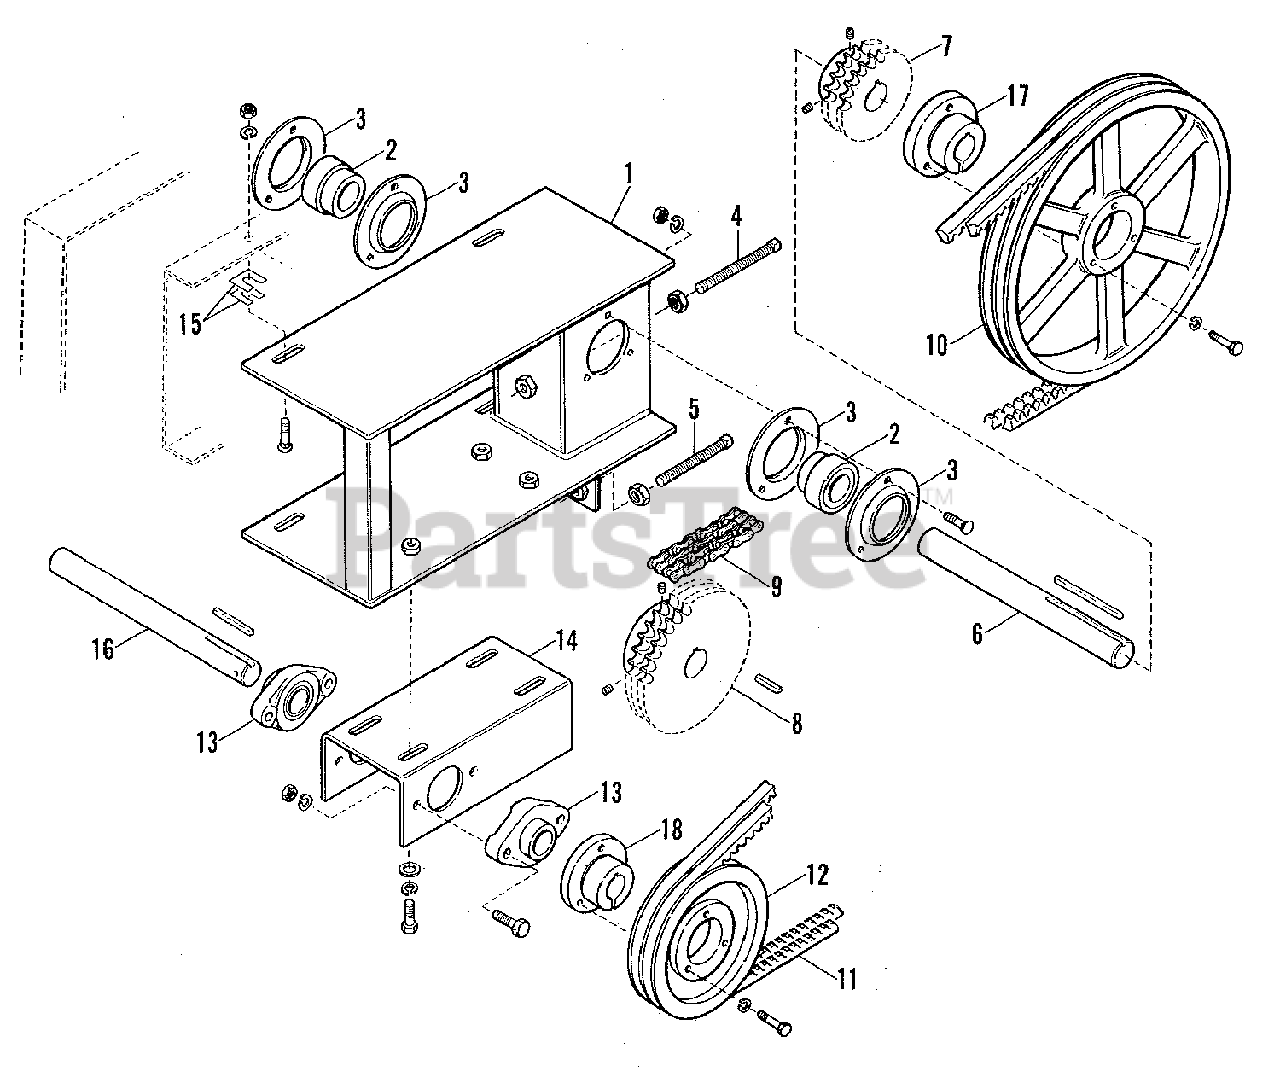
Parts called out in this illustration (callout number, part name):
1	FRAME ASSEMBLY, Mounting
1	BOLT, Carriage, 3/8NC x 1-1/4
1	LOCKWASHER, 3/8
2	BEARING, Reduction Drive Shaft (1-1/4" Bore)
3	FLANGE, Bearing
3	BOLT, Carriage, 3/8NC x 3/4
3	LOCKWASHER, 3/8
4	SETSCREW, 1/2NC x 5
5	SETSCREW, 1/2NC x 4
6	SHAFT, Reduction (Driven)
6	KEY, Square, 1/4 x 1/4 x 3-1/2
7	SPROCKET ASSEMBLY (Double -17T)
7	SETSCREW, Socket Head, 3/8NC x 3/8
8	SPROCKET ASSEMBLY (Double -36T)
8	SETSCREW, Socket Head, 3/8NC x 3/8
8	KEY, Square, 1/4 x 1/4 x 1-5/8
9	CHAIN, Double Strand, #40, 1/2 Pitch (62 Pitches)
9	LINK, Connecting
10	SHEAVE (9-1/4" O.D.)
11	BELT SET, Matched, Set of 2 (46")
13	BEARING ASSEMBLY
13	CAPSCREW, 3/8NC x 1-1/2
13	LOCKWASHER, 3/8
14	BRACKET, Bearing
14	CAPSCREW, 3/8NC x 1
14	WASHER, Plain, 7/16 x 1 x 14 Ga.
14	LOCKWASHER, 3/8
16	SHAFT, Reduction, Drive
16	KEY, Square, 1/4 x 1/4 x 1-3/8
17	BUSHING, 1-1/4" Bore
17	BOLT, Carriage, 1/4NC x 1-1/2
17	LOCKWASHER, 1/4
18	BUSHING, 1" Bore
18	BOLT, Carriage, 1/4NC x 1-1/2
18	LOCKWASHER, 1/4
